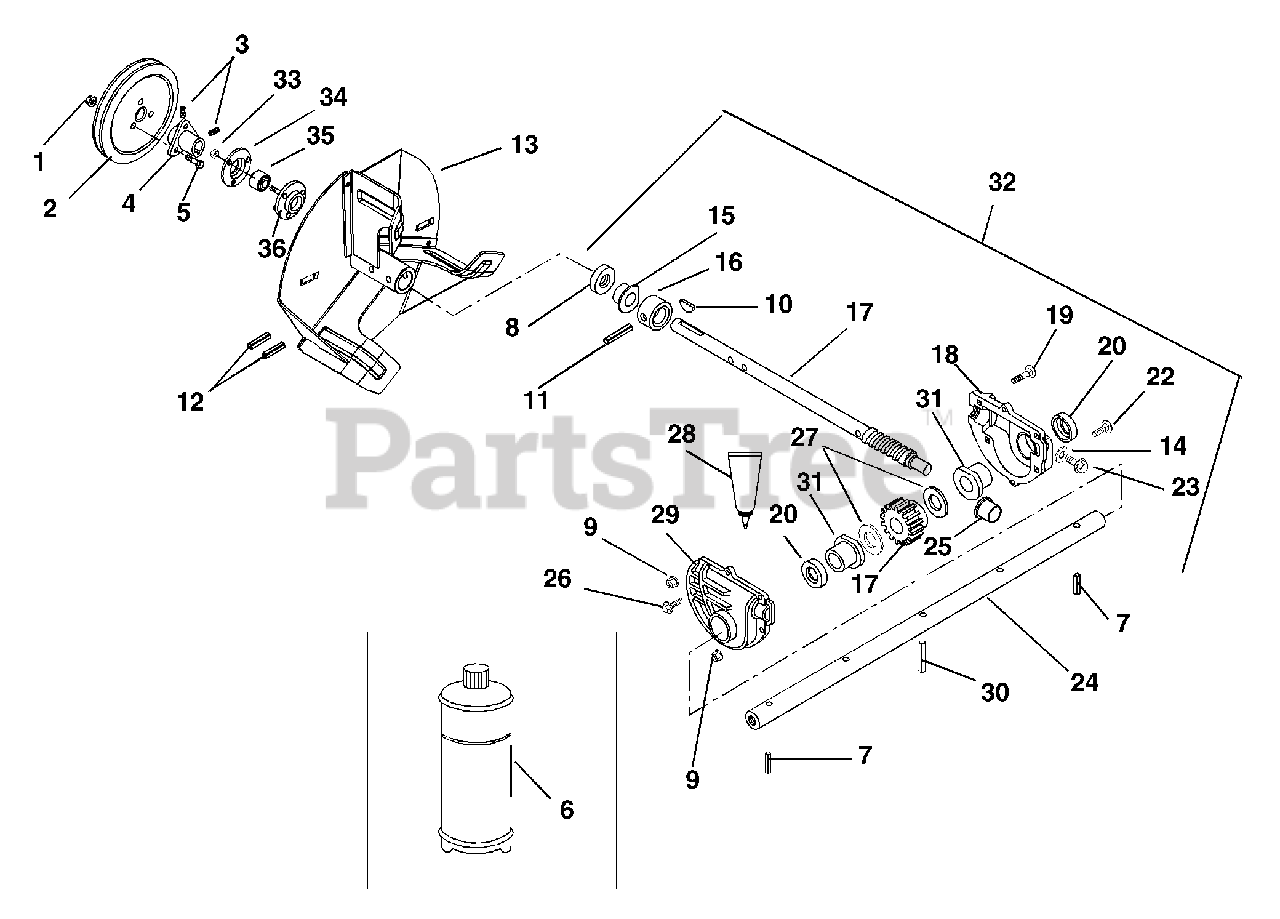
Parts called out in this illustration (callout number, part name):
1	@NUT-SPNLK-FLG .312-18 YWZC
2	PLY-V 8.50 X 1.25 3BLT
2	PLY-V 7.0 X 1.25 3BLT
3	SCR-SET .31-18X.38 SKHCUPDL
4	HUB ASSEMBLY
5	BLT-SERRDHD SL .31-18X.75 YZ
6	ARIENS 16 OZ.BOTTLE OF L2 LUBE
7	PIN-ROLL .188X1.50
8	SEAL-OIL .750X1.375X.250
9	@NUT-SPNLK-FLG .25-20 YWZC
10	KEY-WDRF .188X.875X.375 SAE11
11	PIN-GRV .188X1.25 TP A
12	PIN-ROLL .250X1.75
12	PIN-ROLL .250X1.25
13	IMPELLER - .75 ID X 12" OD
13	IMPELLER - .75 ID X 10" OD
14	WSHR-FIBER .437X.656X.032
15	BSHG-FLG .750X1.000X.750X1.250
16	THRUST COLLAR
17	SHAFT & WORM GEAR ASSEMBLY
17	SHAFT AND WORM GEAR ASSEMBLY
18	CASE, GEAR-LH-LARGE BORE-ALUM.
19	@BLT-RDHDSQNK .25-20X1.25 G5YZ
20	SEAL-OIL 1.000X1.375X.250
22	@BLT-RDHDSQNK .25-20X1.00 G5YZ
23	@SCR-TAP .38-16X.50 HWH TR YWZ
24	SHAFT, RAKE - 24"
24	SHAFT, RAKE - 20"
25	BSHG-FLG .502X1X.750
26	SCR-TAP 10-24X.75 HWH TR YWZC
27	WSHR-HRD-THRS 1.007X1.542X.062
27	WSHR-HDND-THRST .755X1.40X.062
28	LOCTITE GASKET 518--850CC CRTG
28	LOCTITE 518 GASKET--6ML TUBE
29	CASE, GEAR-RH-LARGE BORE-ALUM.
30	PIN-GRV .313X1.44 TP C
31	BSHG-FLG 1.00X1.12
32	GEAR CASE - ALUMINUM - 24"
32	GEAR CASE - 20" - ALUMINUM
32	GEAR CASE - 24" - ALUMINUM
33	@NUT-LK-CTR .25-20 YWZC
34	BEARING FLANGE
35	BRG-BALL .750X1.750X.50
36	BEARING FLANGE
